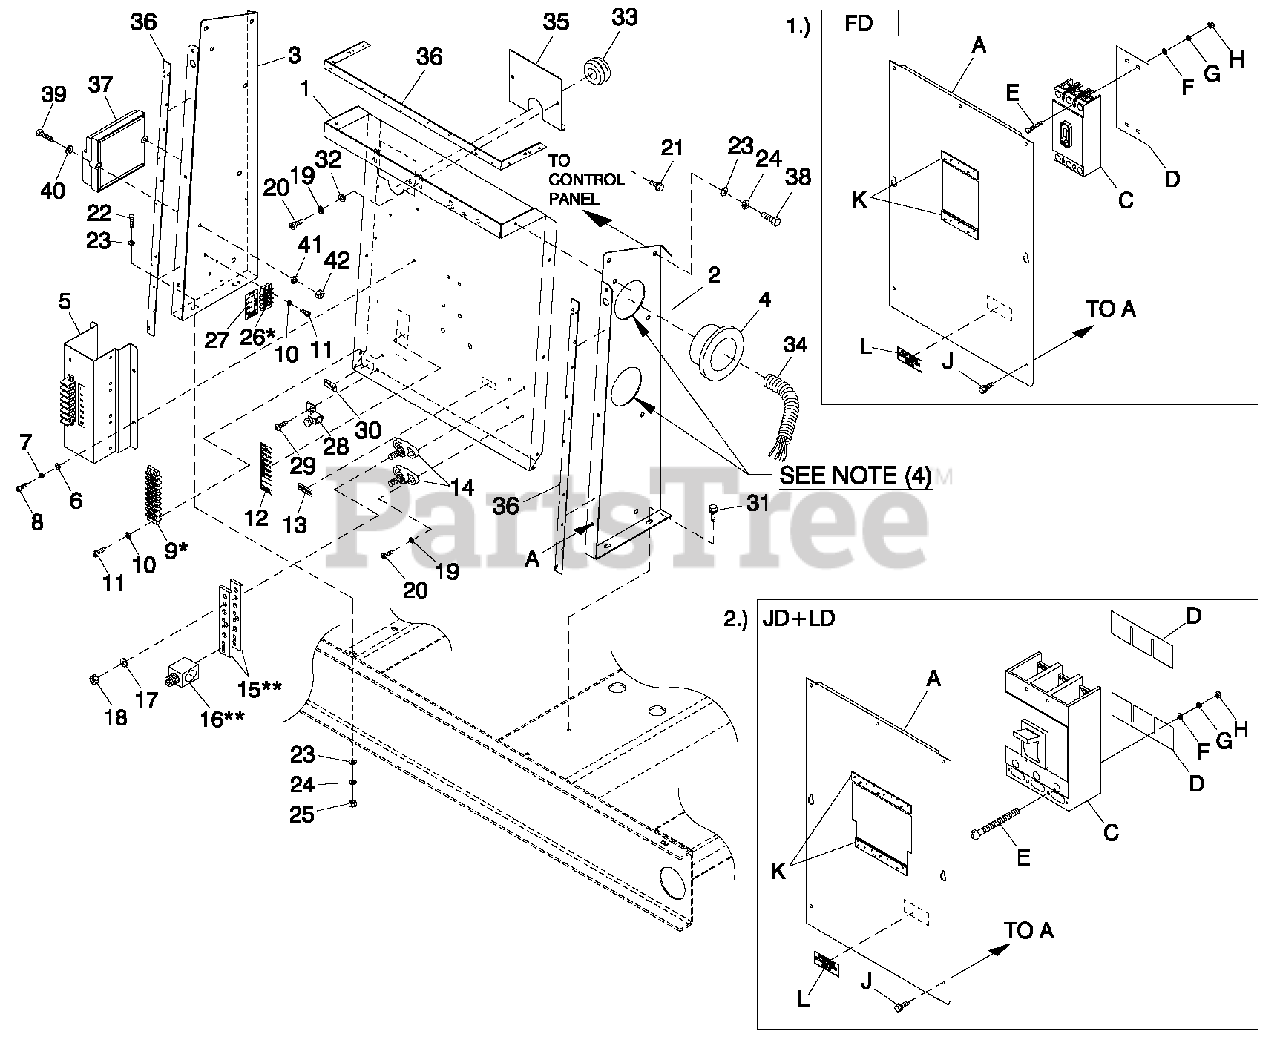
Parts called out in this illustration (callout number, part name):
1	PANEL CB CONN BOX
1	UL CIRCUIT BREAKER (FD)
2	STAND RH CONTROL
2	UL CIRCUIT BREAKER (JD+LD)
3	STAND LH CONTROL C5 GRBX
4	BUSHING SNAP SB-2.5-31
5	ASSY PCB INTERFACE 1PH 240V
6	WASHER FLAT M4
7	WASHER LOC K#8-M4
8	SCREW PHTTM4-0.7X 10 ZYC
9	BLOC K TERM 20A 8 X 6 X 1100V
10	WASHER LOC K#6
11	SCREW PHTT # 6-32X1 /2 ZYC
12	DECAL CPL CUST CONN H CTRL
13	DECAL NEUTRAL
14	JUNCTION BLOC K 3/8-16
15	BUS BAR NEUTRAL BLOC K 390
16	LUG SLDLSS 600/250-1/0 X 1/4-28
17	WASHER LOC K3/8
18	NUT HEX 3/8-16 STEEL
19	WASHERLOCK M5
20	SCREW PHTT M5-0.8X 16 ZYC
21	SCREW THF M6-1 X 16 N WA Z/JS
22	SCREW HHC M6-1.0X20G8.8
23	WASHER FLAT 1/4-M6 ZINC
24	WASHER LOCK M6-1/4
25	NUT HEX M6X 1.0 G8YEL CHR
26	BLOCK TERM 20A 6 X 3 X 1100V
27	DECAL CUST CONN 120V UTILITY
28	LUG SLDLSS #6-14X 13/64 CU
29	SCREW HHTT #10-32X3/8 CZ
30	DECAL GROUND LUG
31	SCREW HHTT M6-1.0X 16ZYC
32	WASHER FLAT M5
33	GROMMET 1.25 X .25 X .75
34	CONDUIT FLEX 2.0" ID
35	PLATE WIRE SNGLGALV
36	TAPE ELEC 1/2 FOAM (AS REQ'D)
37	ASSY PCB 4.6L IGNITION MODULE
38	SCREW HHC M6-1.0X 16 G8.8
39	SCREW PPHM #10 /32X2
40	WASHER FLAT #10 ZINC
41	WASHER LOCK #10
42	NUT HEX #10-32 STEEL
A	COVER FD FRMCB
C	CB0150A3P 600V SFD6 LL
D	INSULATOR CB FD FRAME 30MIL
E	SCREW SHC 1/4-20 X 4 G8.8 NZ
F	WASHER FLAT 1/4-M6 ZINC
G	WASHER LOCK M6-1/4
H	NUT HEX 1/4-20 STEEL
J	SCREW THF M6-1 X 16 N WA Z/JS
K	TAPE ELEC 1/2 FOAM (AS REQ'D)
L	DECAL CUSTOMER CONNECT INSIDE
A	COVER C IRBRKRJD/LD
C	CB0300A3P 600V SJD6 LL
D	INSULATOR CIRCUIT BR. JD/LD
E	SCREW RHM 1/4-20X3
